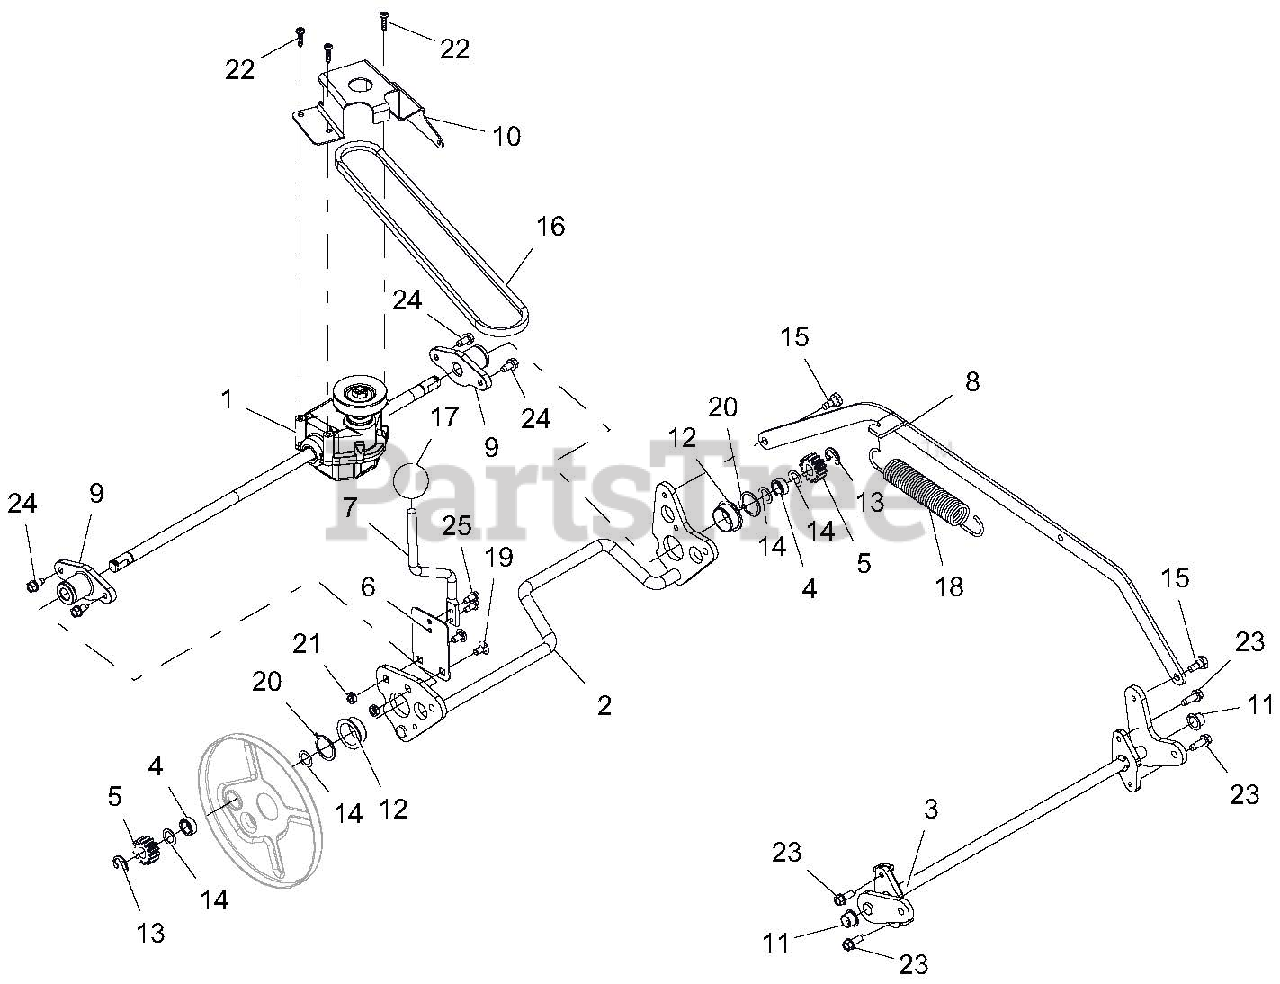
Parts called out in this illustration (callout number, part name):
1	TRANSAXLE, AUTOMATIC, LM, 9:1
2	WLDMT, REAR AXLE
3	WMT, LM FRONT AXLE
4	BSHG, SPCR.500X.750X.321 PM
5	GEAR, PINION, LM WHEEL DRIVE
6	PLATE, HOC SPRING
7	LEVER, HOC ADJUSTMENT
8	LINK, HOC CONNECT
9	HUB, LM REAR AXLE
10	BRKT, TRANSMISSION BELT GUIDE
11	BUSHING, POLYLINER-.50 SPLIT
12	BSHG-FLG 1.0X1.125X.50X1.375 R
13	RG-RTNG-EXT .500X.042 (E)
14	WASHER, .500X.750X.020 THRUST
15	BOLT, SHLDR .320X.210X.25-20
16	V-BELT, 3L-WRAPPED
17	KNOB,BALL -BLACK 1.47" .375-16
18	SG-TENS .121X1.00X6.5 WLD 12
19	@BLT-RDHDSQNK .25-20X.50 G5YZ
20	RG-RTNG-EXT 1.00X.042
21	NUT-LK-CTR JAM .25-20 YWZC
22	SCR-TAP 10-14X.75PLSTITE BLKOX
23	SCR-TAP-PM .25-20X.75 TR YWZ
24	SCR-TAP .25-20X.50 HWH TR YWZ
25	@SCR-TAP 12-24X.50 HWH TR YWZC
